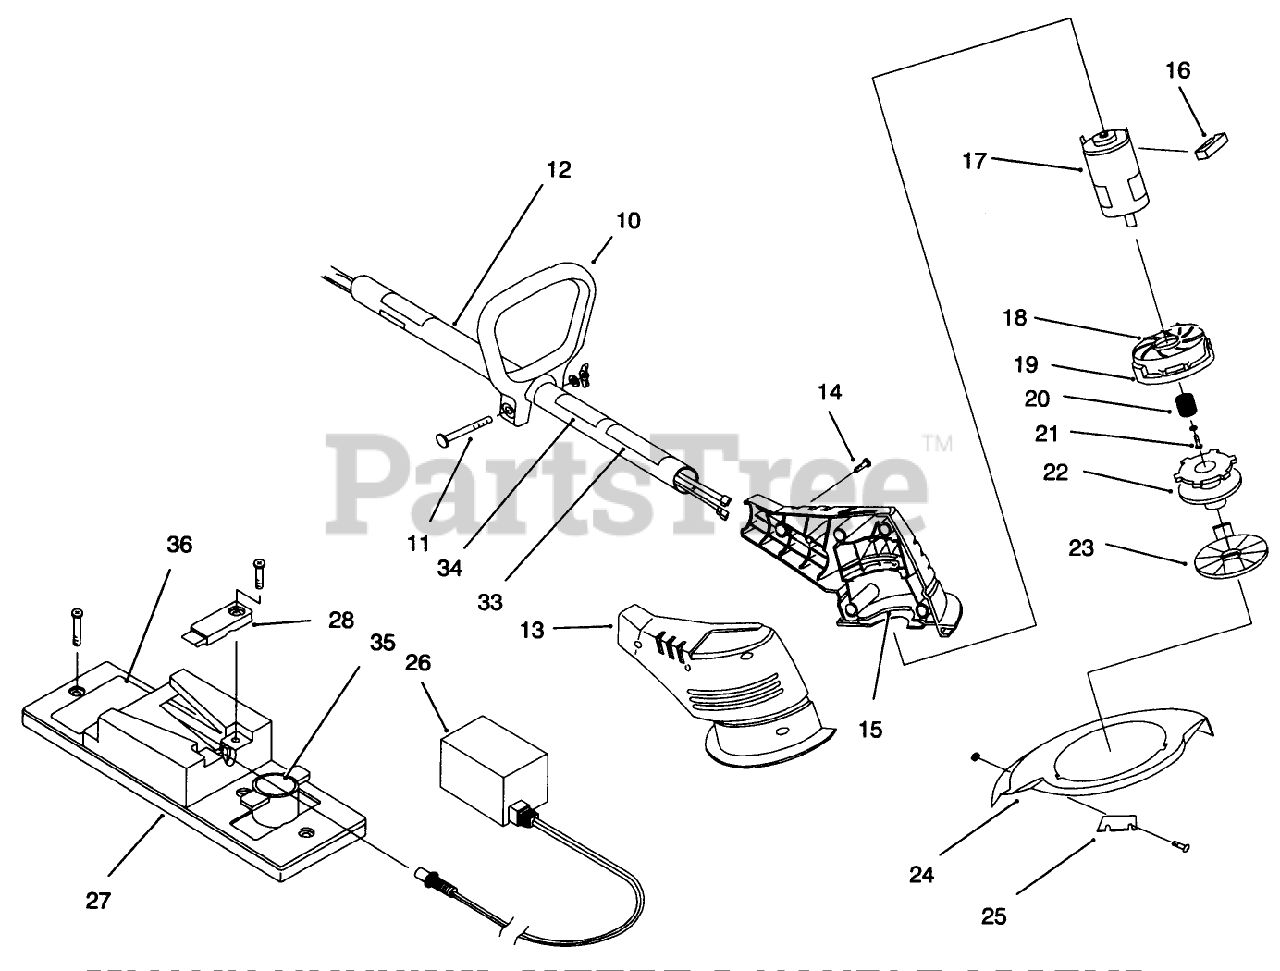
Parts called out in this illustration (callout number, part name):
11	HARDWARE - D-HANDLE
12	ASSEMBLY - BOOM
13	HOUSING - MOTOR
18	OUTER SPOOL & EYELET
20	SPRING
24	ASM - GUARD & BLADE
25	ASSEMBLY - BLADE
27	ASSEMBLY - WALL STATION
34	DECAL - UL SAFETY WARNING
